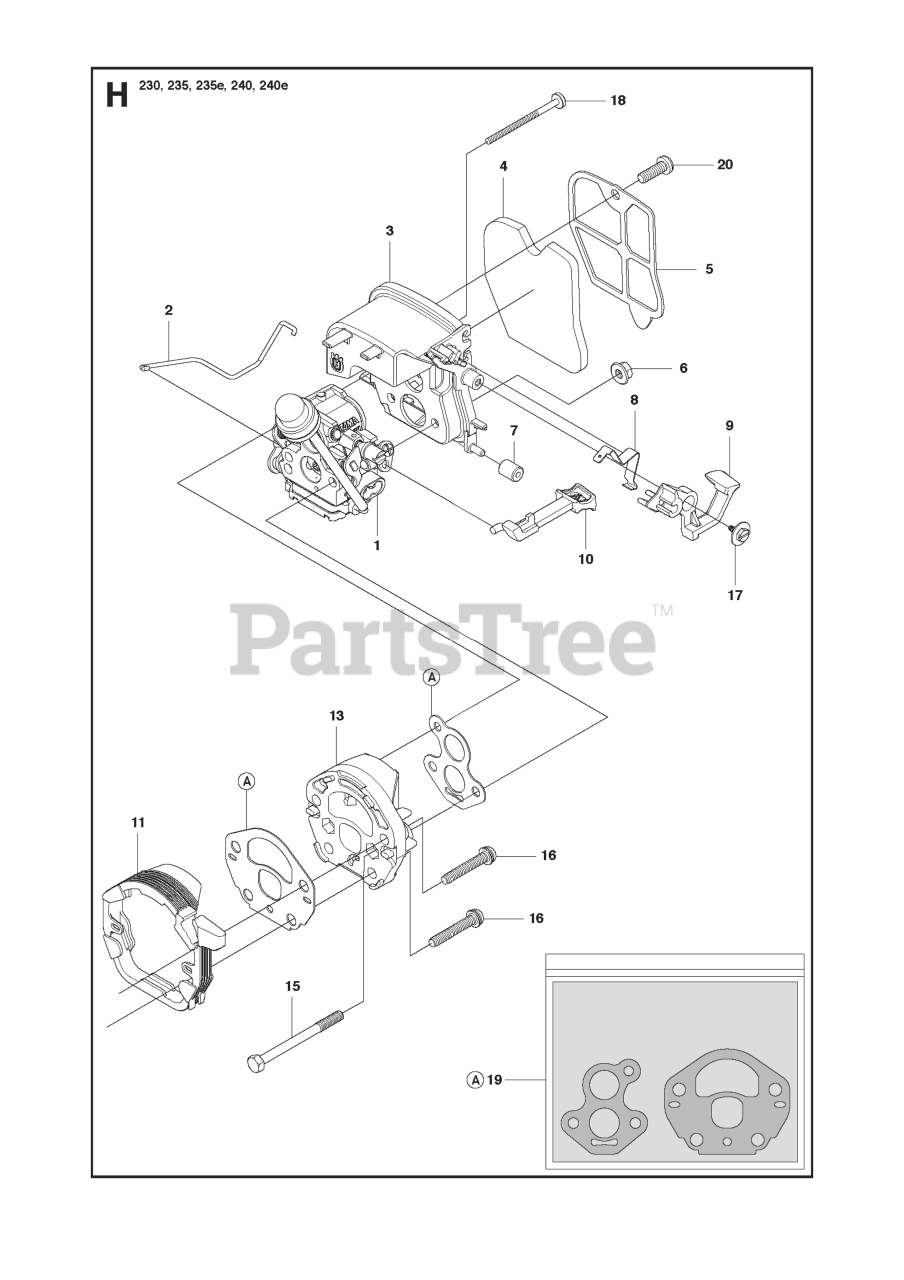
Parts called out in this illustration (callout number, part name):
1	%CARBURETOR
2	THROTTLE WIRE
3	FILTER HOUSING
4	AIR FILTER
7	ISOLATOR FILTER HOUSING
9	SWITCH LEVER
10	CHOKE KNOB
11	CARB ADAPTOR SEAL
13	CARB ADAPTOR
15	STUD CARBURETOR
18	TOP STUD - CARBURETOR
19	GASKET KIT
20	SCREW FILTER PLATE
